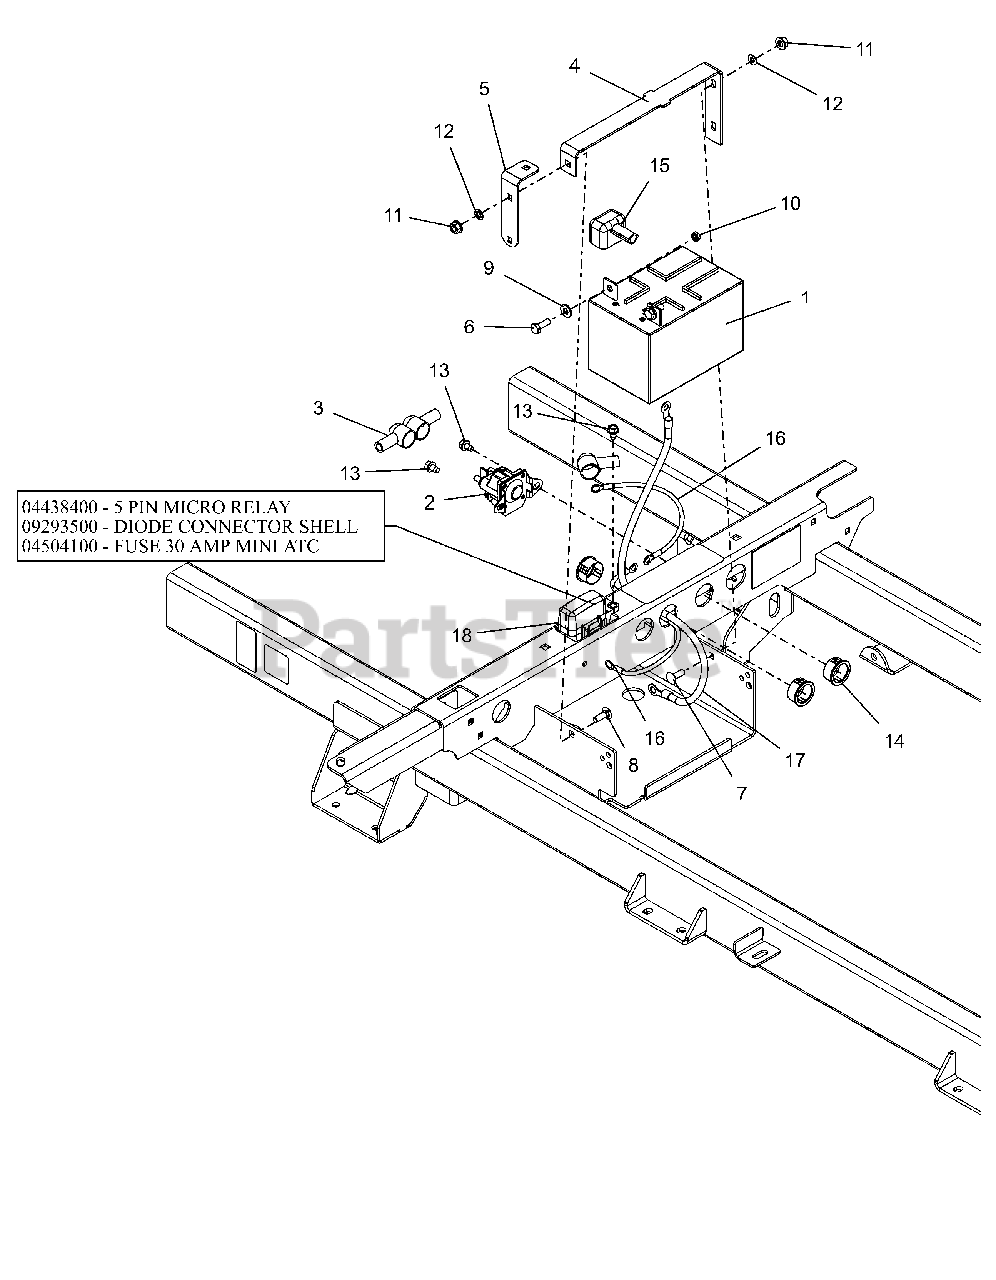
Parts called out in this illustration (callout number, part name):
1	BATTERY, 12V 12A-190CCA
2	SOLENOID, STARTER (SEALED)
3	BOOT, EYELET TERMINAL
4	BRKT, BATTERY HOLD-DOWN
5	BRKT, BATTERY HOLD DOWN
6	@BLT-HEX .25-20X.75 GR5 YWZC
7	@BLT-RDHDSQNK .25-20X.75 G5YZ
8	@BLT-RDHDSQNK .25-20X.75 G5YZ
9	@WSHR-FL-STL.281X.62X.065 YWZC
10	NUT, 10-24 KEPS
11	@NUT-LK-TOP-FLG .25-20 YWZC
12	NUT-PUSH .25X.50 O.D.
13	@SCR-TAP .25-20X.37 HWH YWZ TR
14	BSHG, PANEL SNAP .937X1.11X.56
15	INSULATOR
16	CABLE,POS W/2 1/4 RING 15.0 LG
17	CABLE-NEGATIVE BATTERY 24.00"
18	HARNESS, WIRE-4POS KEY IKON/ZT
18	RELAY,MICRO5 TERML W/RESISTOR
18	DIODE, CONNECTOR SHELL
18	FUSE,30 AMP MINI-ATC
